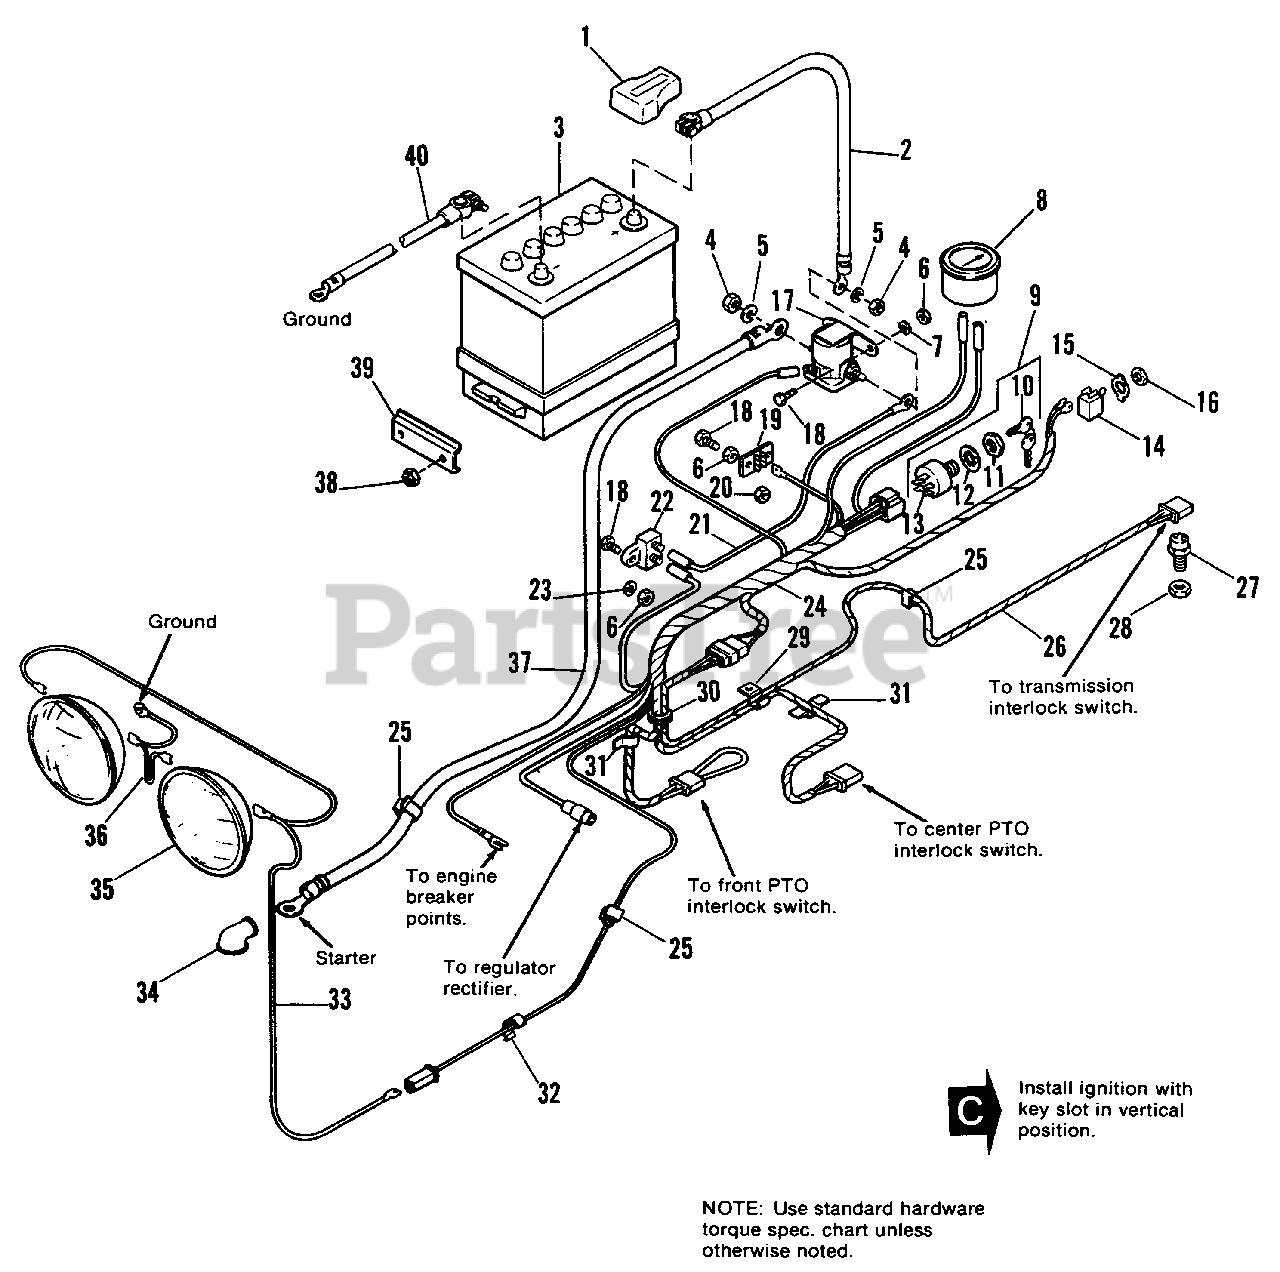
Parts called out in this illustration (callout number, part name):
1	PROTECTOR, Terminal
2	CABLE, Battery to Solenoid
3	BATTERY (includes decal)
4	NUT, Hex, 5/16-18
5	LOCKWASHER. 5/16
6	LOCKNUT, Hex, 1/4-20
7	LOCKWASHER, 1/4
9	SWITCH & KEY ASSY., Ignition
11	NUT, Special
12	LOCKWASHER, Internal Tooth, 5/8
13	SWITCH, Ignition
14	SWITCH, Toggle
16	NUT, Switch
17	SOLENOID, Starter
18	CAPSCREW, Hex Hd., 1/4-20 x 5/8
19	BOARD, Terminal
20	LOCKNUT, Hex, 1/4-20
22	CIRCUIT BREAKER
23	LOCKWASHER. 1/4
24	HARNESS ASSY.
25	CLIP, Tinnerman
26	WIRE ASSY.
27	SWITCH, Interlock
28	NUT, Pal
29	CLIP, Cable
31	CLIP, Wire
32	CLIP, Tinnerman
34	COVER, Terminal
36	WIRE ASSY.
37	CABLE, Solenoid to Starter
38	NUT, Elastic, 5/16-18
40	CABLE, Battery to Ground
